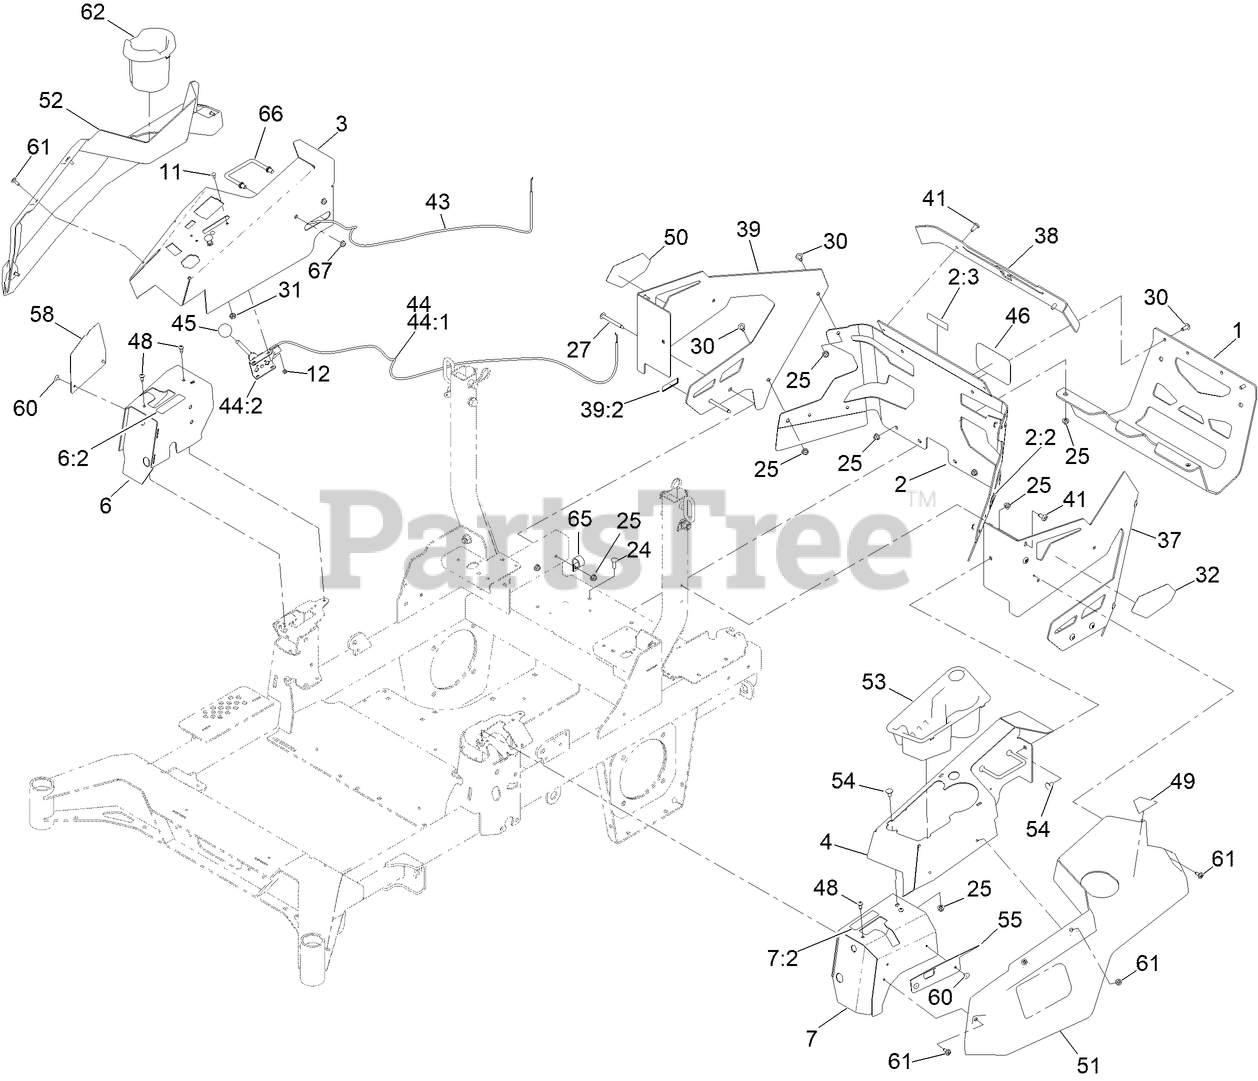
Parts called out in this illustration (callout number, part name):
1	GUARD-MUFFLER [BLACK]
2	REAR GUARD ASM
2:2	DECAL-WARNING
2:3	DECAL-HITCH
3	CONSOLE-RH
4	CONSOLE-LH
6	RH COVER ASM
6:2	DECAL-CONTROL, MOTION
7	LH COVER ASM
7:2	DECAL-CONTROL, MOTION
11	BOLT-CARR
12	NUT-LOCK, NI
24	SCREW-CARR
25	NUT-HF, NI
27	SCREW-TORX
30	SCREW-TORX
31	NUT-HJ
32	DECAL - 4000 SERIES, LH
37	GUARD-REAR, LH
38	GUARD-REAR, TOP
39	RH REAR GUARD ASM
39:2	DECAL-ARRESTOR, SPARK
43	CABLE-CHOKE CONTROL
44	THROTTLE CONTROL ASM
44:1	LEVER-THROTTLE
45	KNOB-BALL
48	SCREW-TPH THD FORM
49	DECAL-FILL, FUEL
50	DECAL-4000 SERIES, RH
51	SIDE POD, LH
52	SIDE POD, RH
53	CUP HOLDER
54	SCREW-CARR
55	PLATE-COVER, LH FRONT
58	PLATE-COVER, RH FRONT
60	RIVET-TRIFOLD
61	SCREW-SHOULDER
62	CUPHOLDER-RH
65	R-CLAMP
66	ROD-SUPPORT, POD
